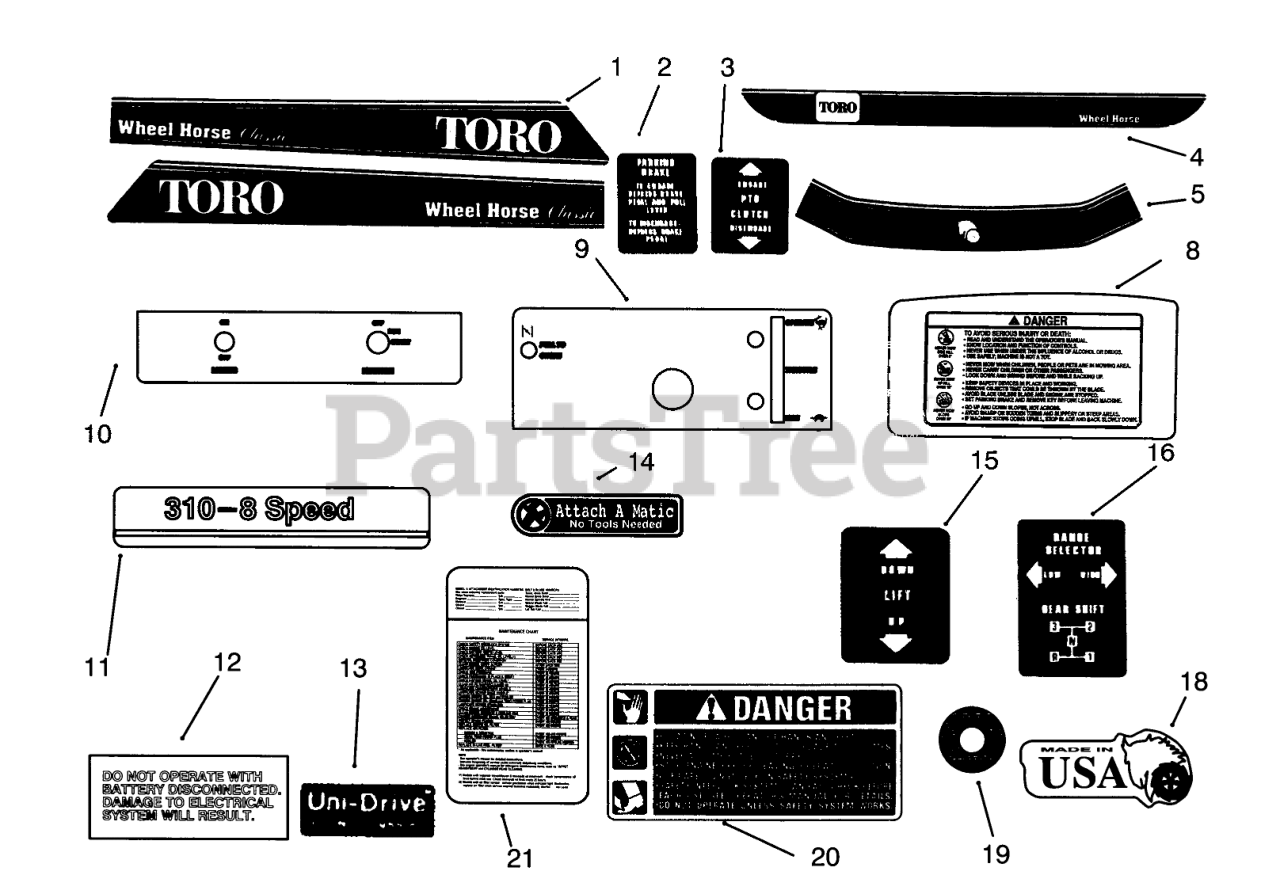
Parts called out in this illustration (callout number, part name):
1	DECAL-HOOD CLASSIC
2	DECAL-PARKING, BRAKE
3	DECAL PTO CLUTCH
4	DECAL-FENDER
5	DECAL-FRONT HOOD
8	Decal-Danger
9	DECAL-CONSOLE
10	DECAL-BACK PLATE
11	Decal-310-8 Speed
12	DECAL ELECT SYSTEM
13	Decal-Unidrive
14	Decal-Attac-O-Matic
15	DECAL-LIFT
16	DECAL-SHIFT PATTERN
18	Decal-Made In USA
19	Decal-Air Cleaner
20	DECAL-DANGER
21	Decal-Maintenance
